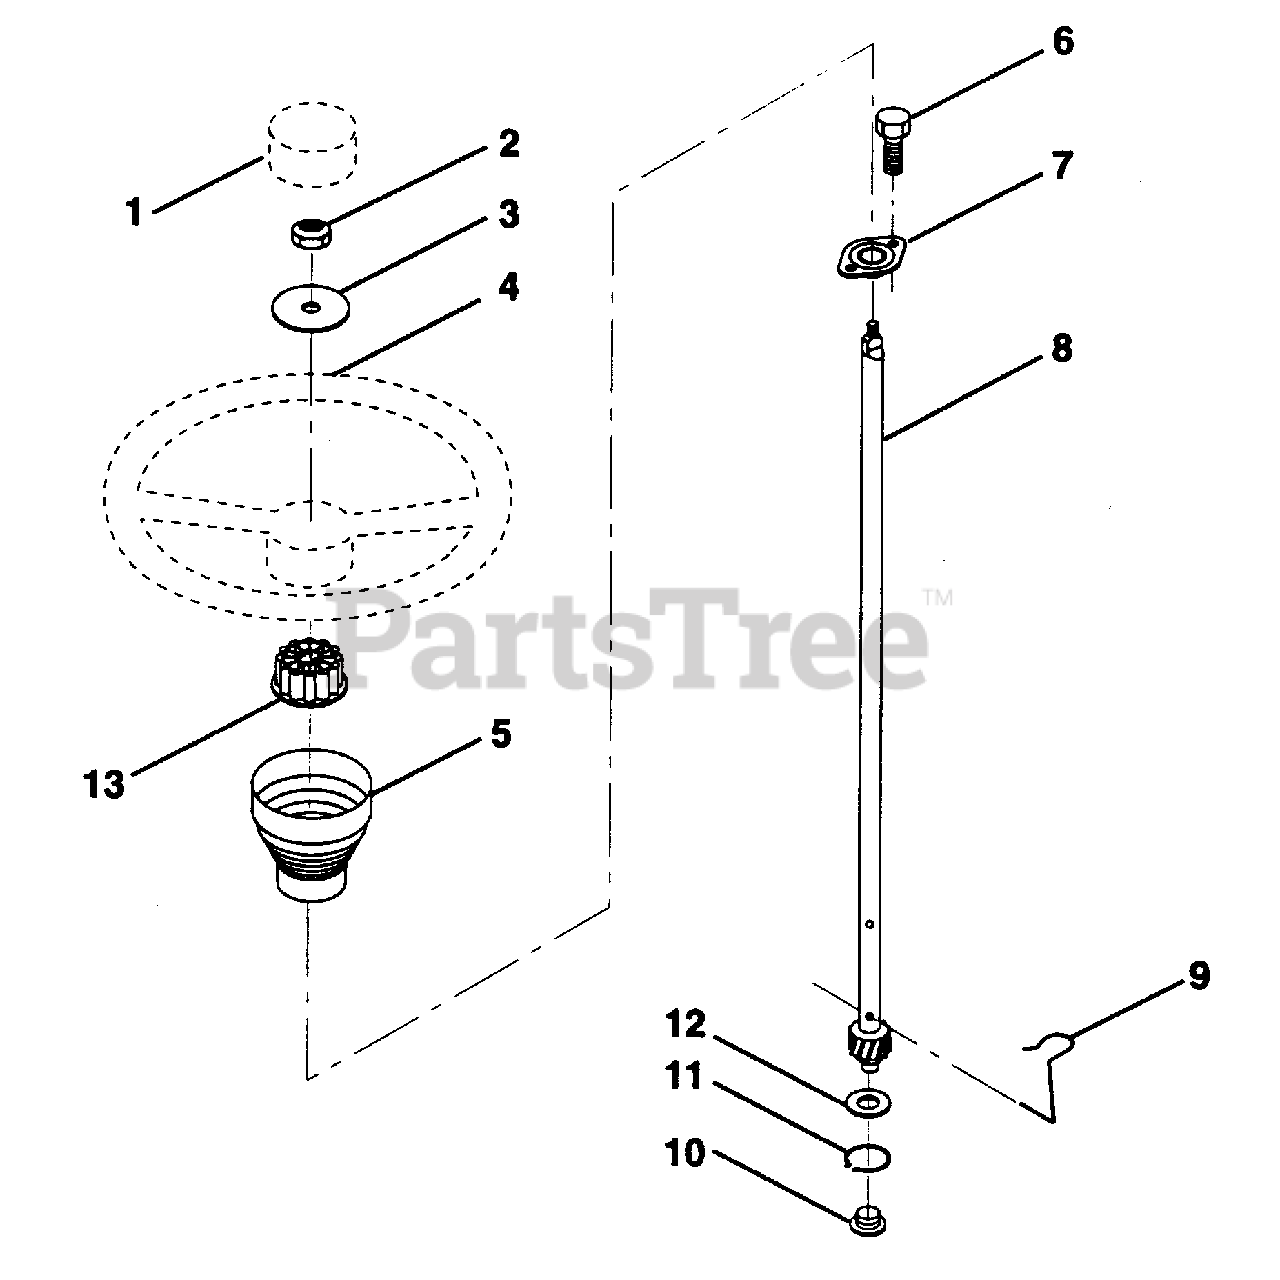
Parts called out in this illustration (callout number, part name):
1	Insert, Wheel, Steering
2	Nut, Lock 3/8-24 UNF
3	Washer 12/32 x 2-3/8 x 8 Ga.
4	Wheel, Steering
5	Sleeve, Steering
6	Screw, Hex #10-16 x 1/2 TY-B
7	Bushing, Steering
8	Shaft, Steering
9	Clip, Steering
10	Bushing, Lower, Steering
11	Ring, Retaining
12	Washer 21/32 x 1 x 16 Ga.
13	Adaptor, Wheel, Steering
